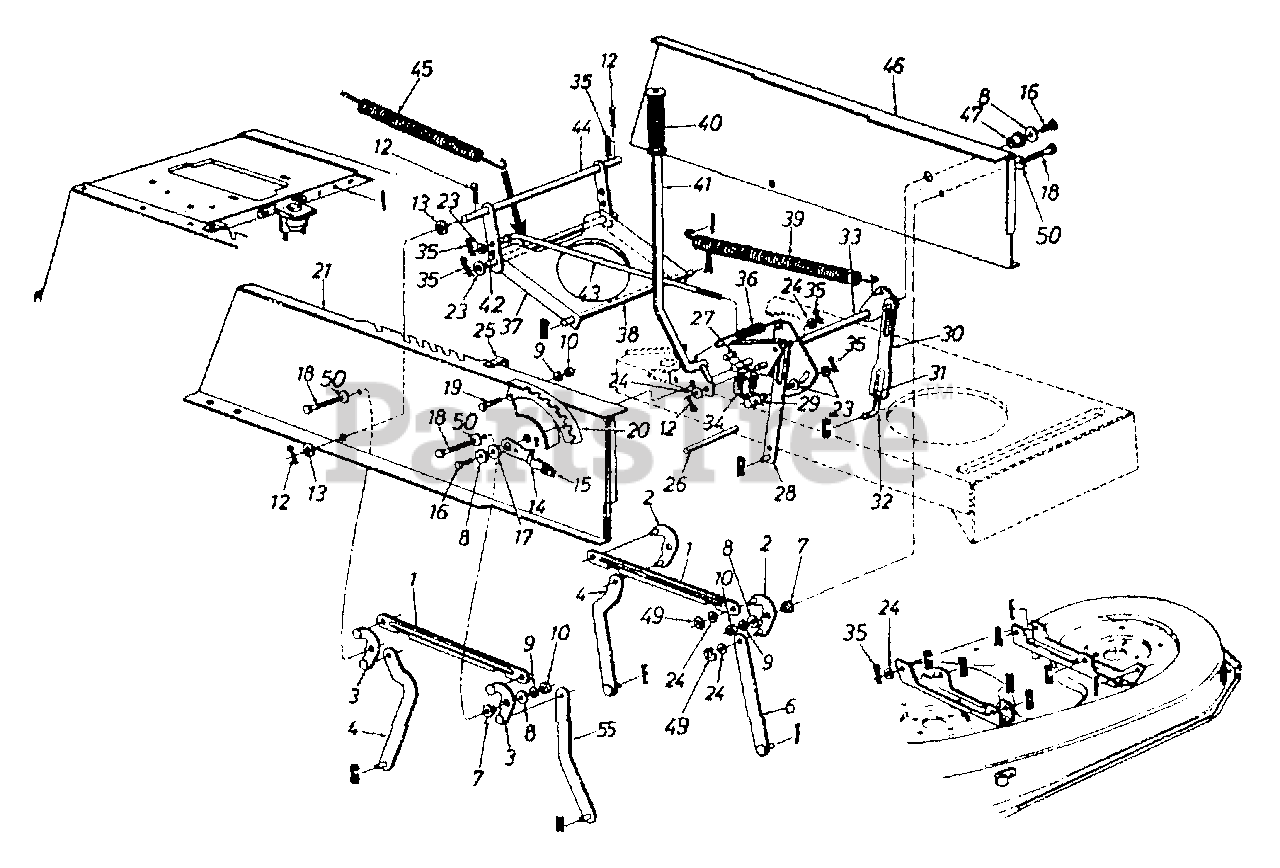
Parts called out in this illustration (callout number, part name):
3	Pivot Link Assembly.-RH
7	Shld. Spacer .318" I.D.
8	Flat Washer .344" I.D. x 1.125" O.D.
9	Lock Washer 5/16" I.D.
10	Hex Nut 5/16-18 Thd.
12	Cotter Pin 1/8" Dia.
13	Flat Washer .635" I.D. x 1.0" O.D.
14	Hgt Adj. Stop Lever Assembly
15	Knob
16	Hex Washer Screw 5/16-18 x .625"
17	Flange Bearing .63" I.D.
18	Hex Wash. Hd. Scr. 5/16-18 x .875"
19	Hex Bolt 5/16-18 x .75" Lg.
20	Index Brkt.
24	Flat Washer .531" I.D. x .93" O.D.
25	Clamp
26	Running Board Rod
27	Hex Wash. Hd. Tap Scr.
31	Hex Nut 1/2-20 Thd.
32	Lift Link Adjuster
35	Inter. Cotter Pin 3/8" Dia.
36	Extension Spring
39	Extension Spring
40	Grip (Lift Handle)
43	Disengagement Rod
49	"E"-Ring
50	Washer .325" I.D.
